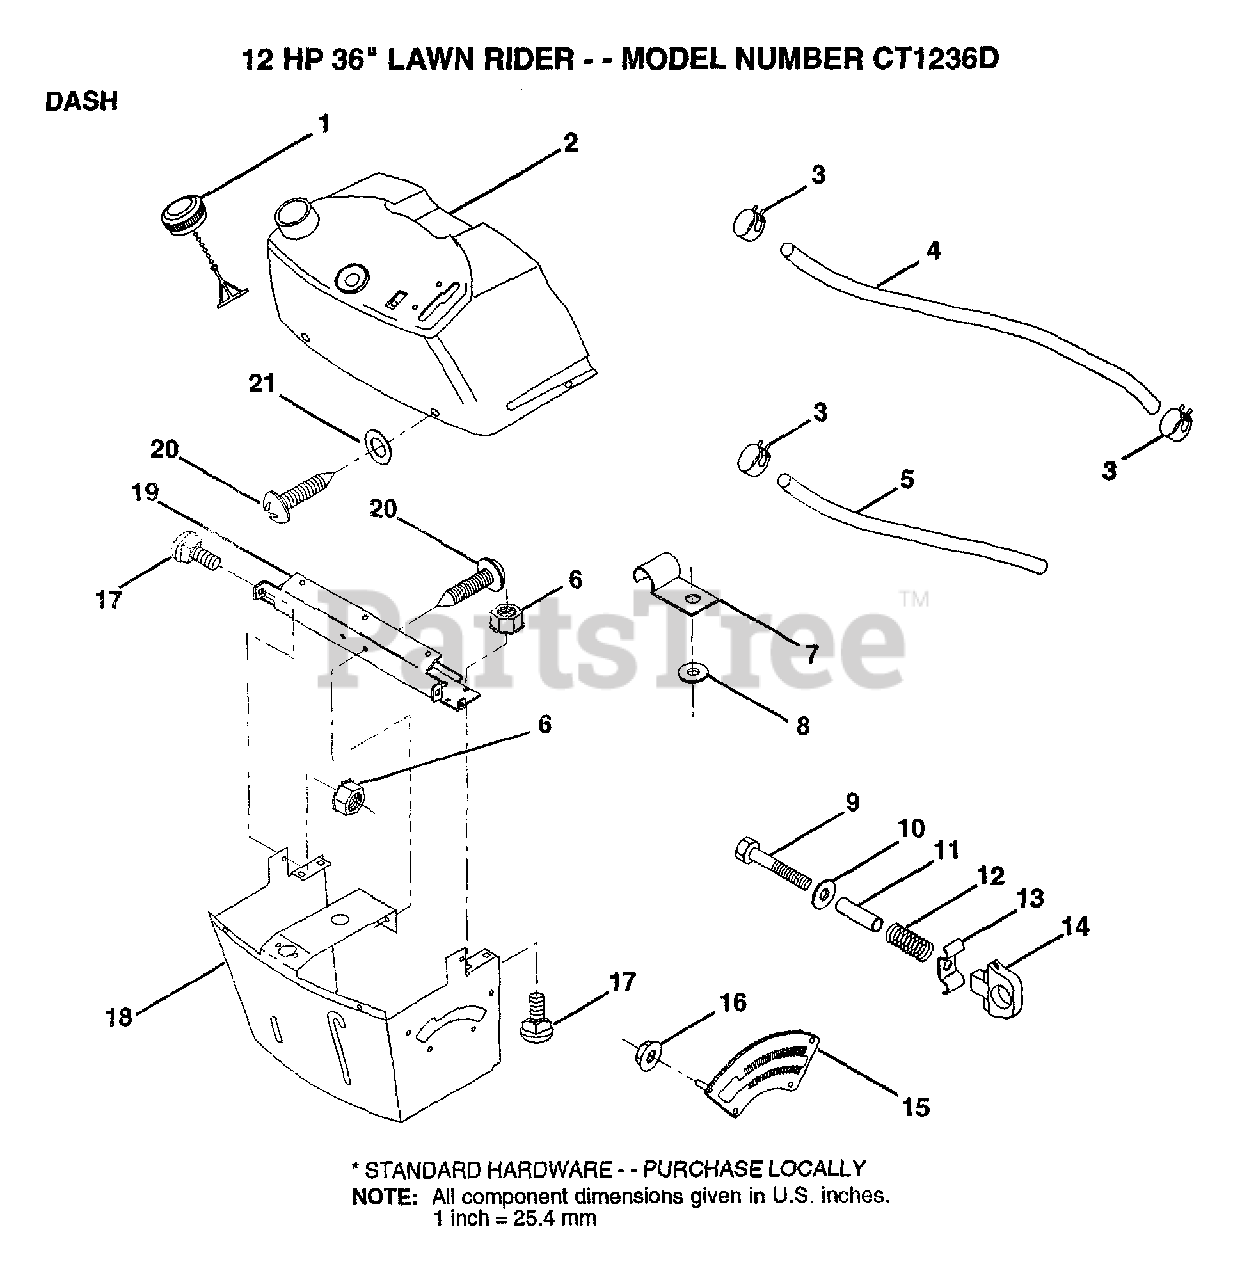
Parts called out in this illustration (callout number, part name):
3	HOSE CLAMP
5	FUEL LINE T
6	NUT
7	CLIP T
8	WASHER PM
9	BOLT
11	SPACER SPLIT
12	SPRING M
13	"KNOB,HGT RETAINER"
14	KNOB
15	ADJUSTER QUAD
16	NUT
17	BOLT
18	SUPT ASSY DASH
